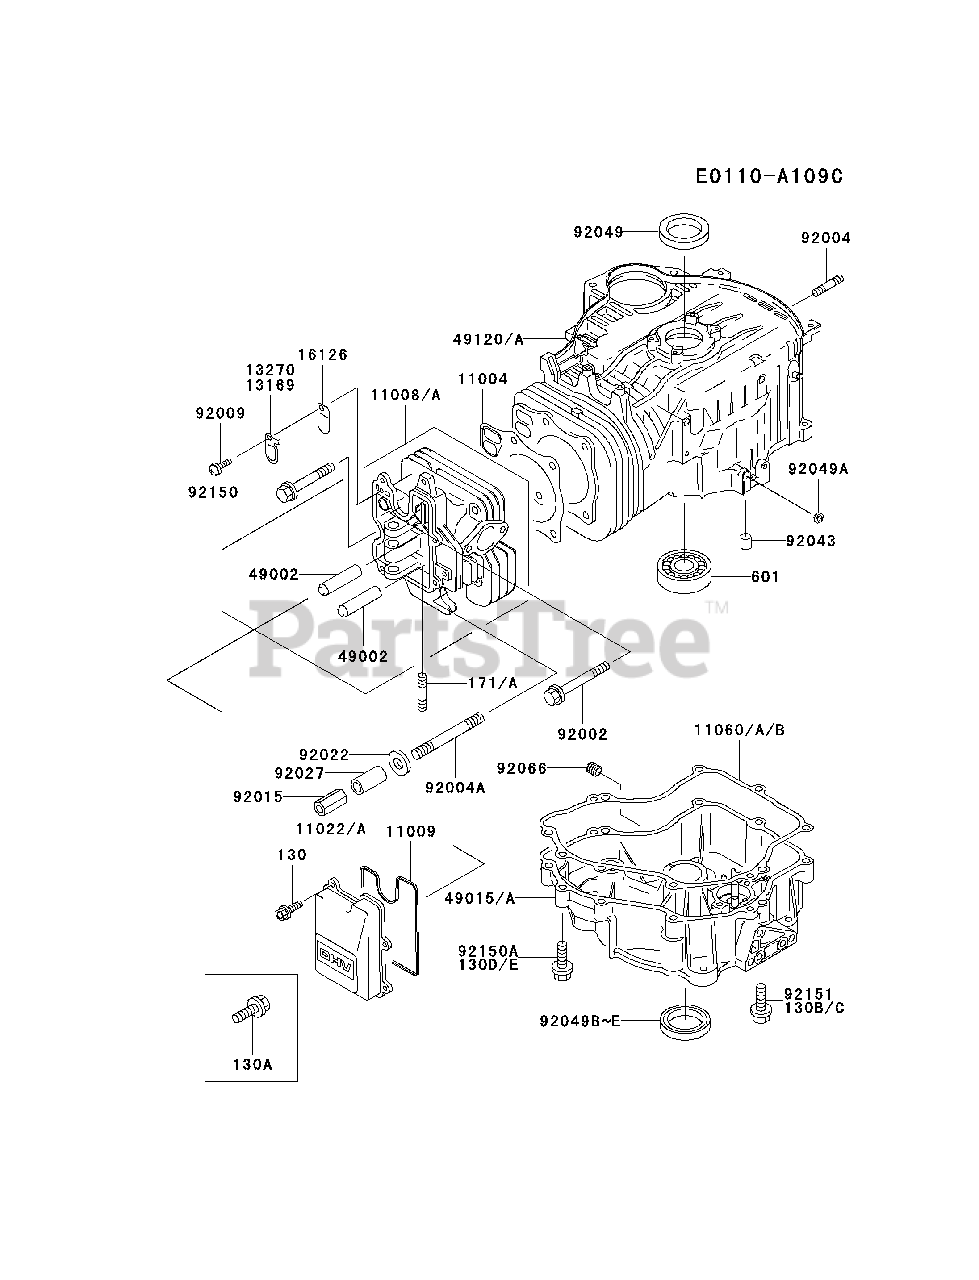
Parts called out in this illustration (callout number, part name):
130D	BOLT-FLANGED
171	BOLT-STUD
601	BEARING,BALL
